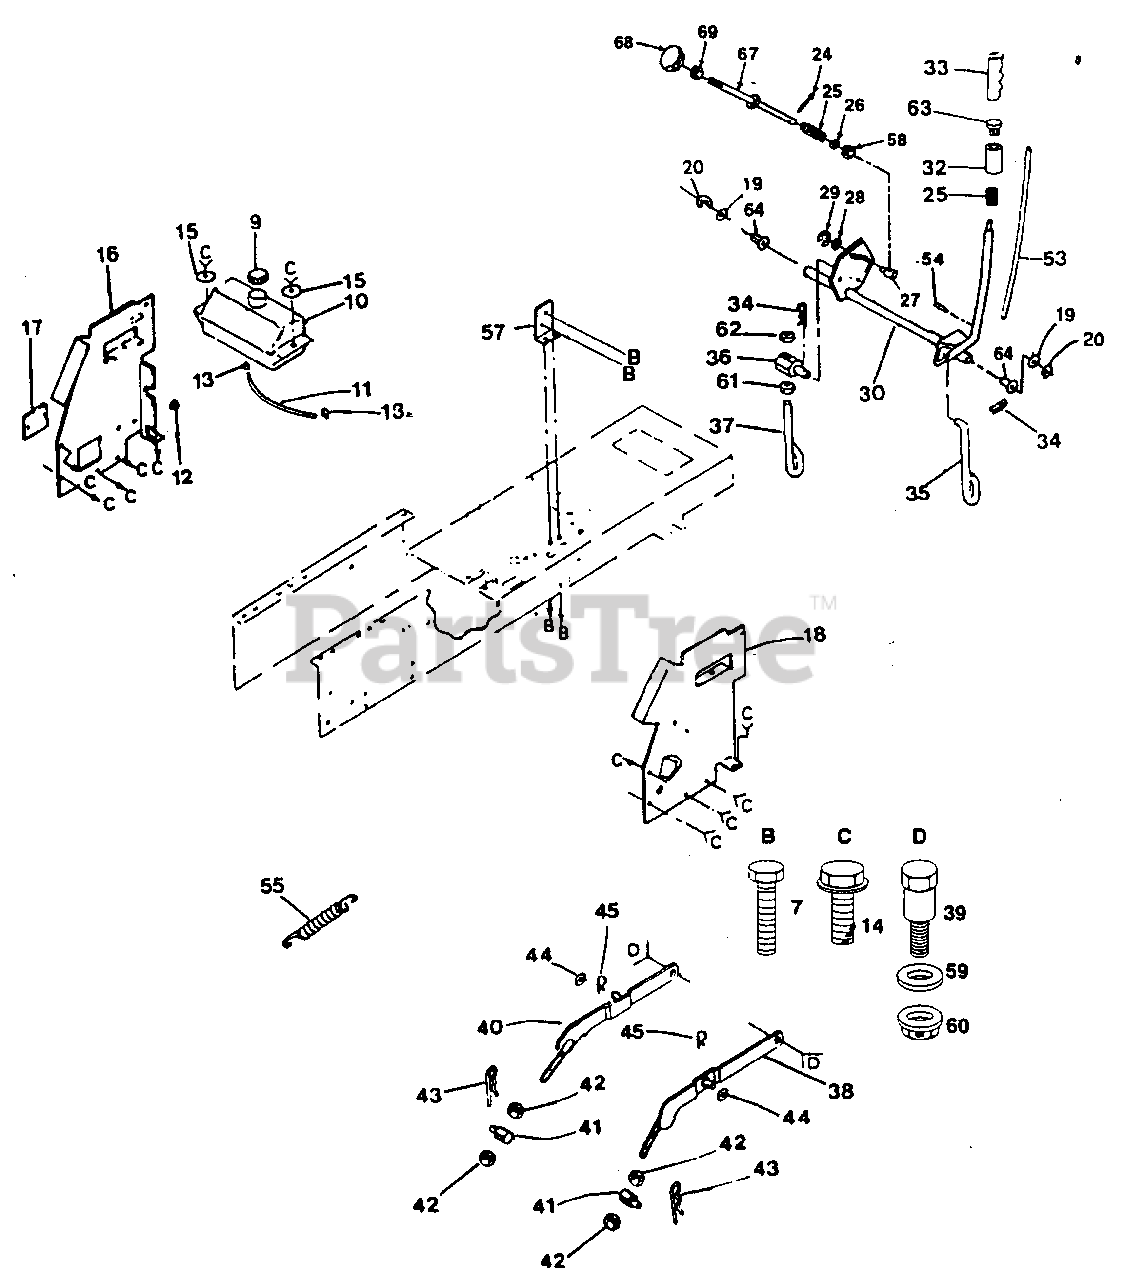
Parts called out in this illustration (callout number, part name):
7	Screw, Hex., Tapping, #10-24 x 1/2
9	Cap, Fuel
10	Tank, Fuel
11	Line, Fuel
14	Screw, Hex, Washer Head, Thread Rolling 1/4-20 x 3/4
15	Washer 9/32 x 7/8 x 16 Ga.
16	Panel, Dash, L. H.
17	Cover, Access
18	Panel, Dash, R. H.
19	Washer 21/32 x 7/8 x 16 Ga.
24	Pin, Cotter 3/32 x 1/2
26	Washer 13/32 x 5/8 x 16 Ga.
27	Trunnion, Depth Stop
28	Washer 15/32 x 3/4 x 16 Ga.
29	Ring, Klip #T5304-37
32	Plunger
33	Grip, Handle
34	Retainer, Spring
36	Trunnion, Lift
37	Link, Lift, Adjustable
38	Arm, Suspension, R. H.
39	Bolt, Shoulder 3/8-16
40	Arm, Suspension, L. H.
41	Trunnion, Lift, Lower
42	Nut, Hex 1/2 - 13
43	Retainer, Spring
44	Washer 17/32 x 15/16 x 16 Ga.
45	Retainer, Spring
55	Spring, Extension
57	Bracket, Switch
59	Washer, Spring
60	Locknut, Flange 3/8-16
61	Nut, Hex, Jam 7/16-20
62	Nut, Crownlock 7/16-20
63	Plunger, Button
64	Washer, Nylon
67	Lever, Assembly
69	Rod, Lift Adjust
